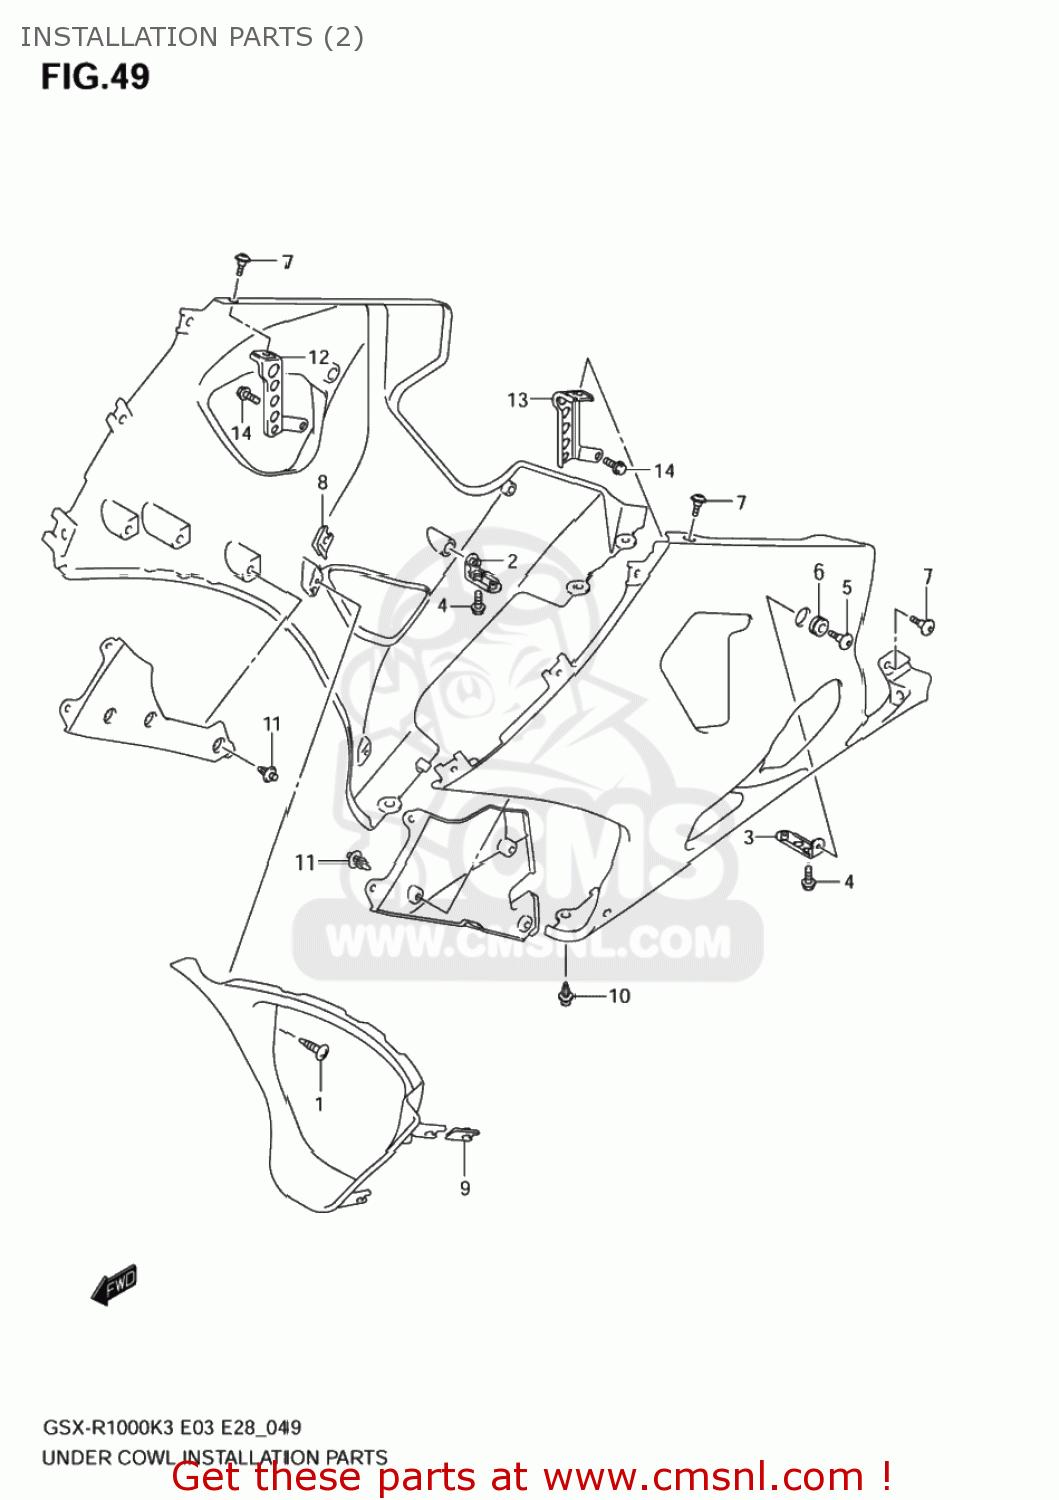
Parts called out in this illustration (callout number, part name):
1	SCREW
2	BRACKET,UNDER COWLING LWR,R
3	BRACKET,UNDER COWLING LWR,L
4	BOLT
5	SCREW(6X20)
6	CUSHION
7	SCREW(5X13)
8	NUT
9	NUT,COWL
10	CLIP
11	CLIP(BLACK)
12	BRACKET,COWLING,R
13	BRACKET,COWLING,L
14	BOLT
